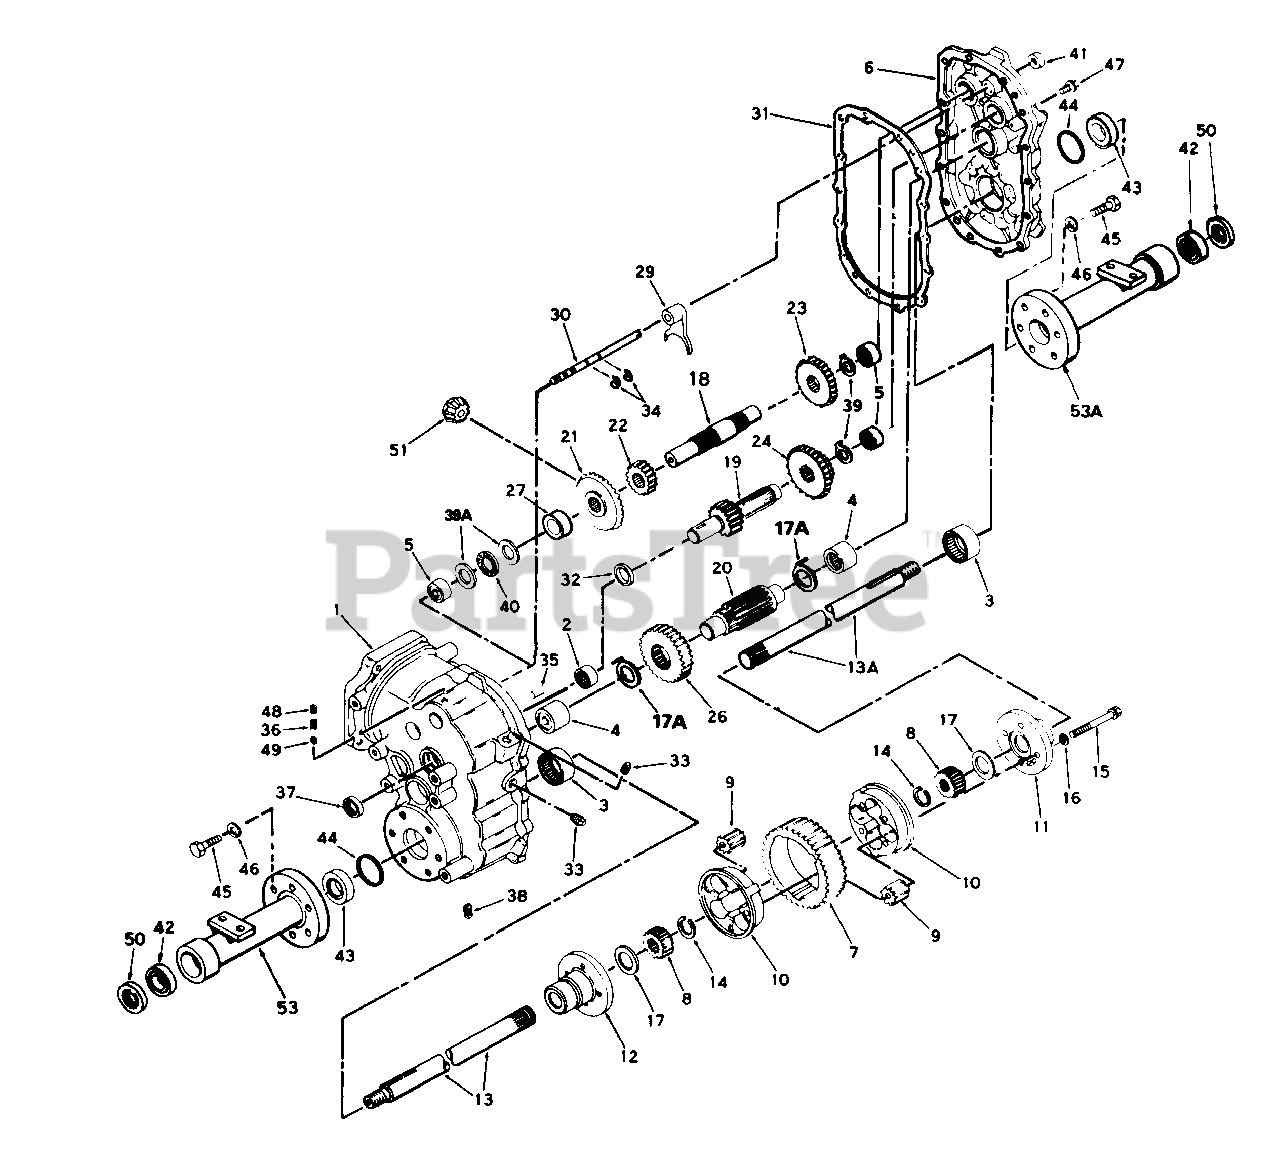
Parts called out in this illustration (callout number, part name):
1	Case Ass'y., Transaxle
2	Bearing, Needle
3	Bearing, Needle
4	Bearing, Needle
5	Bearing, Needle
6	Cover Ass'y., Transaxle
7	Gear, Ring
8	Gear, Side
9	Gear, Pinion
10	Core, Body
11	Carrier, Differential
12	Carrier, Differential
13	Axle, (18-17/64" Long)
13A	Axle, (15-29/64" Long)
14	Ring, Snap
15	Screw, Hex Hd. Mach., 3/8-16 x 3-3/8
16	Lock Washer, 3/8"
17	Washer, Thrust
17A	Washer, Thrust
18	Shaft, Counter
19	Shaft, Brake
20	Pinion, Output
21	Gear, Bevel (30 Teeth)
22	Gear, Spur (16 Teeth)
23	Gear, Spur (23 Teeth)
24	Gear, Cluster (20 and 27 Teeth)
26	Gear, Output (37 Teeth)
27	Spacer (55/64" Long)
29	Fork, Shift
30	Rod, Shift
31	Gasket, Case and Cover
32	Spacer
33	Plug, Pipe
34	Ring, Snap
35	Pin, Dowel
36	Spring
37	Seal, Oil
38	Plug, Magnetic Drain
39	Washer, Thrust
40	Bearing, Thrust
41	Seal, Oil
42	Bearing, Ball
43	Bearing, Thrust
44	Seal, Square Cut
45	Screw, Hex Hd. Mach., 1/2-13 x 1 1/2
46	Lock Washer, 1/2"
47	Screw, Hex Hd. Thd. Forming, 5/16-18 x 1
48	Screw, Set 1/4-20 x 1/2
49	Ball, Steel
50	Seal, Oil
51	Pinion, Bevel
53	Housing, Axle (9-1/4" Long)
53A	Housing, Axle (7-5/16" Long)
